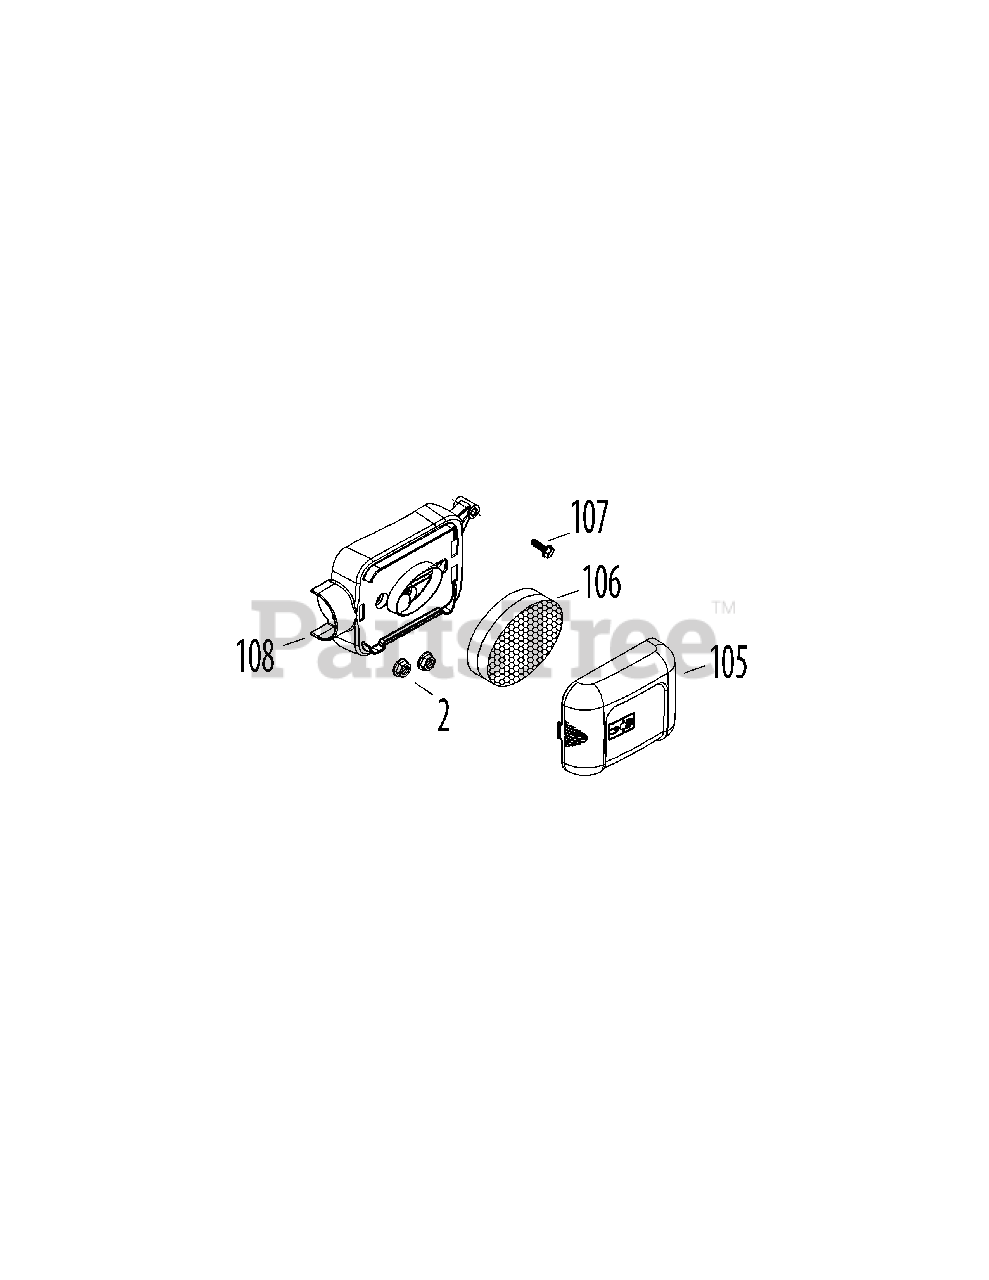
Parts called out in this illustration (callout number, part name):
2	Nut M6 X 10 Mm
105	Outer Air Filter Cover
106	Air Filter Element, Oval
107	A/F Base Bolt M6×30
108	Inner Air Filter Housing
